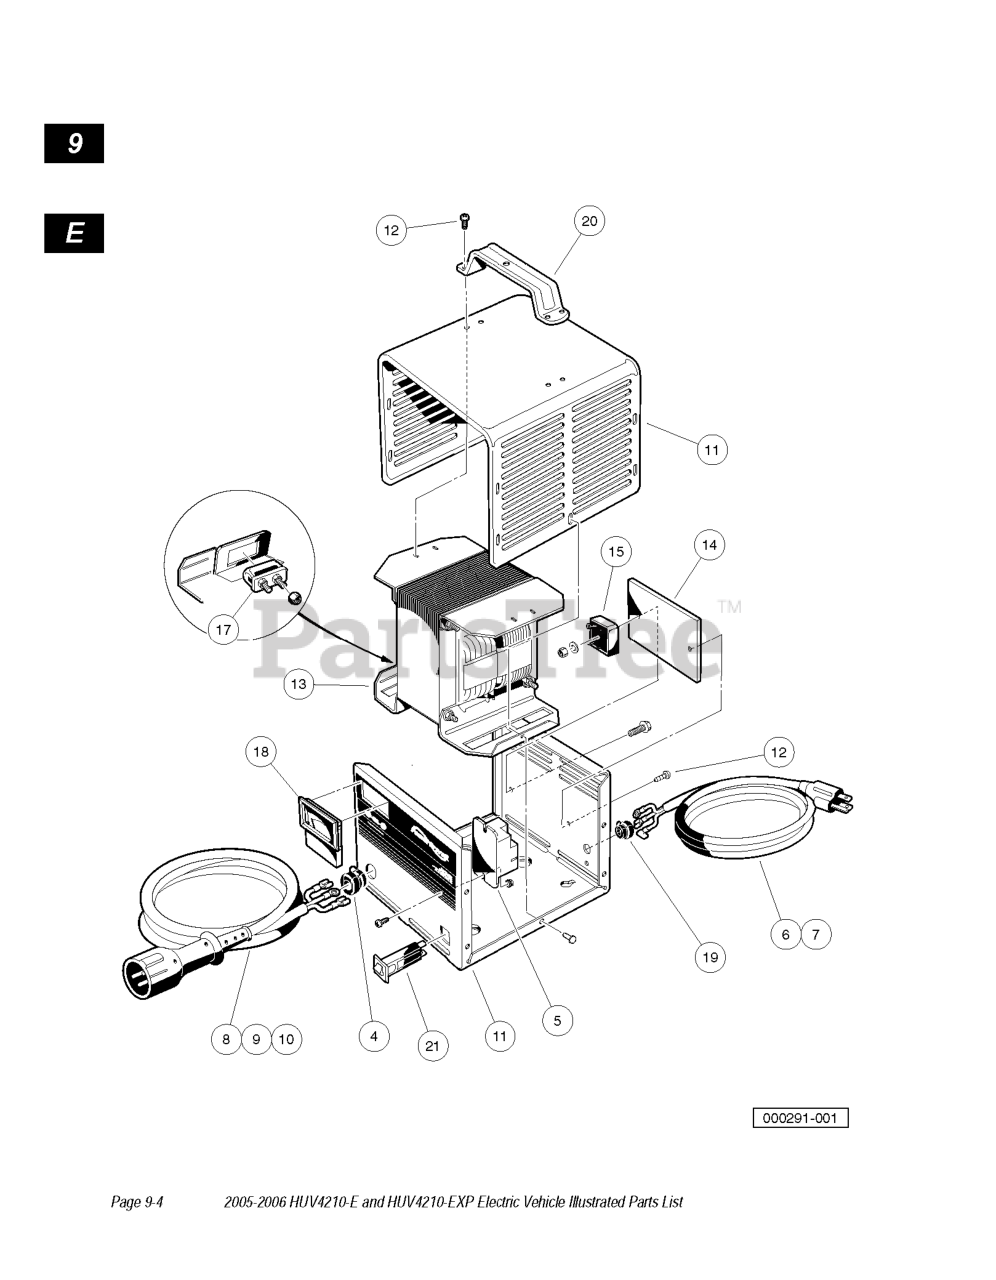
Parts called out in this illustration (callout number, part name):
4	DC CORD BUSHING
5	PD 48V POWER RELAY
6	AC CORDSET 80 INCH
7	AC CORDSET 108 INCH
8	PD2 DC CORDSET 113 INCH
9	PD2 DC CORDSET 154 INCH
10	PD2 DC CORDSET 250 INCH
12	SCREW, #10 X .50 PHIL PAN HEAD
13	PD2 TRANSFORMER ASM
14	PD2 HEATSINK
15	PD2 DIODE BRDGE W/ FILM
16	PD2 WIRE ASM
17	PD2 FUSE ASM
18	PD2 AMMETER
19	PD2 AC CORD BUSHING
20	PD2 HANDLE
21	CIRCUIT BREAKER, 15A/120V
